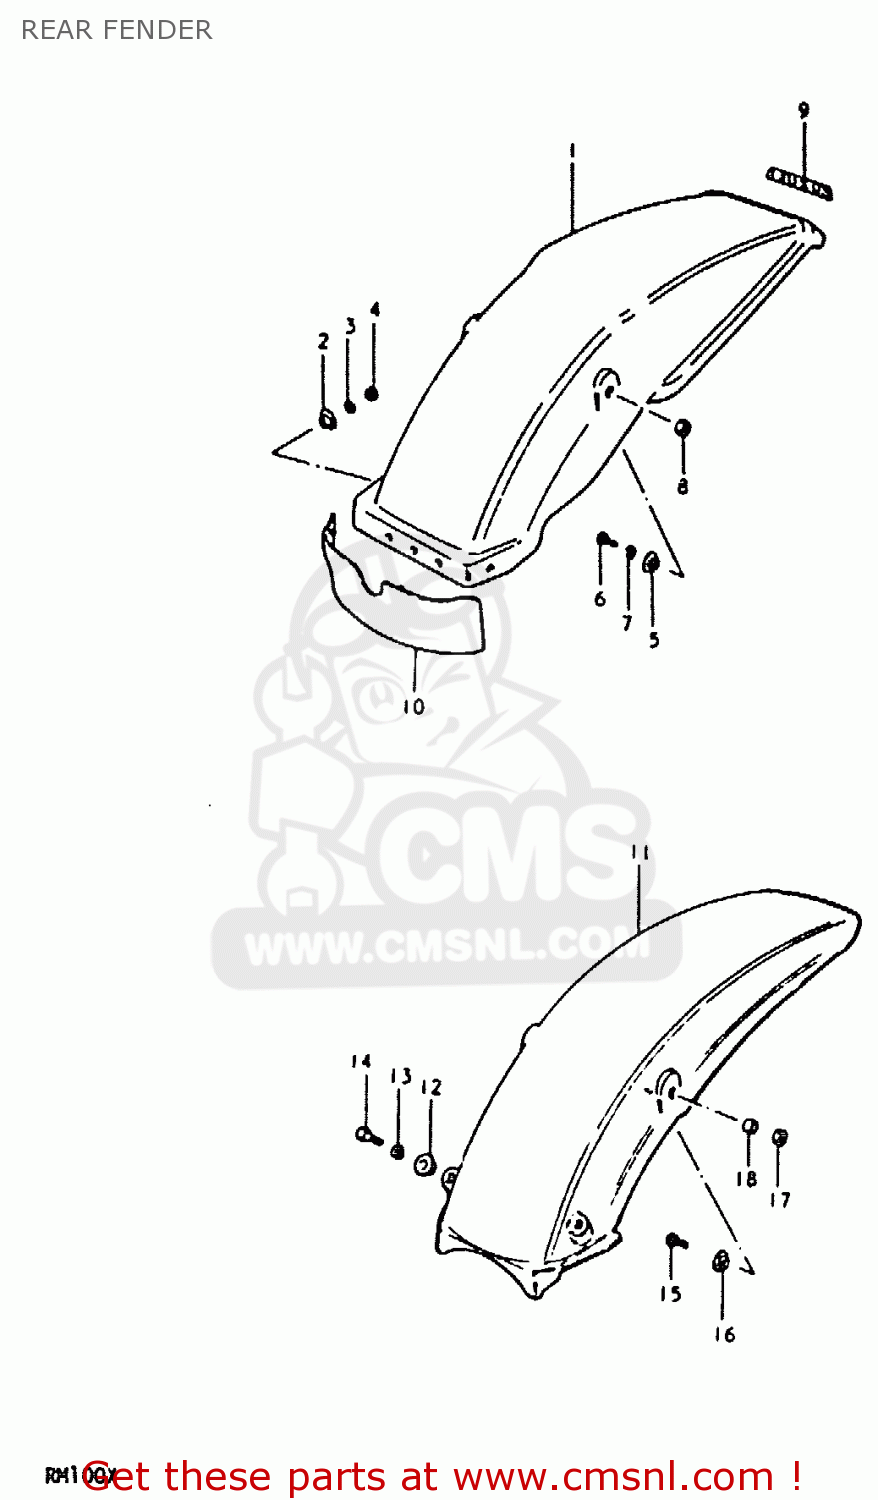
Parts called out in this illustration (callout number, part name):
1	FENDER,REAR
2	WASHER
3	LOCK WASHER
4	NUT
5	WASHER
6	BOLT, UPPER
7	LOCK WASHER
8	NUT 6MM
9	EMBLEM,FRONT FENDER
10	MUD GUARD,REAR FENDER
11	FENDER,REAR
12	WASHER
13	LOCK WASHER
14	BOLT, UPPER
15	SCREW
16	WASHER (6.5X20X1.2)
17	NUT
18	SPACER
